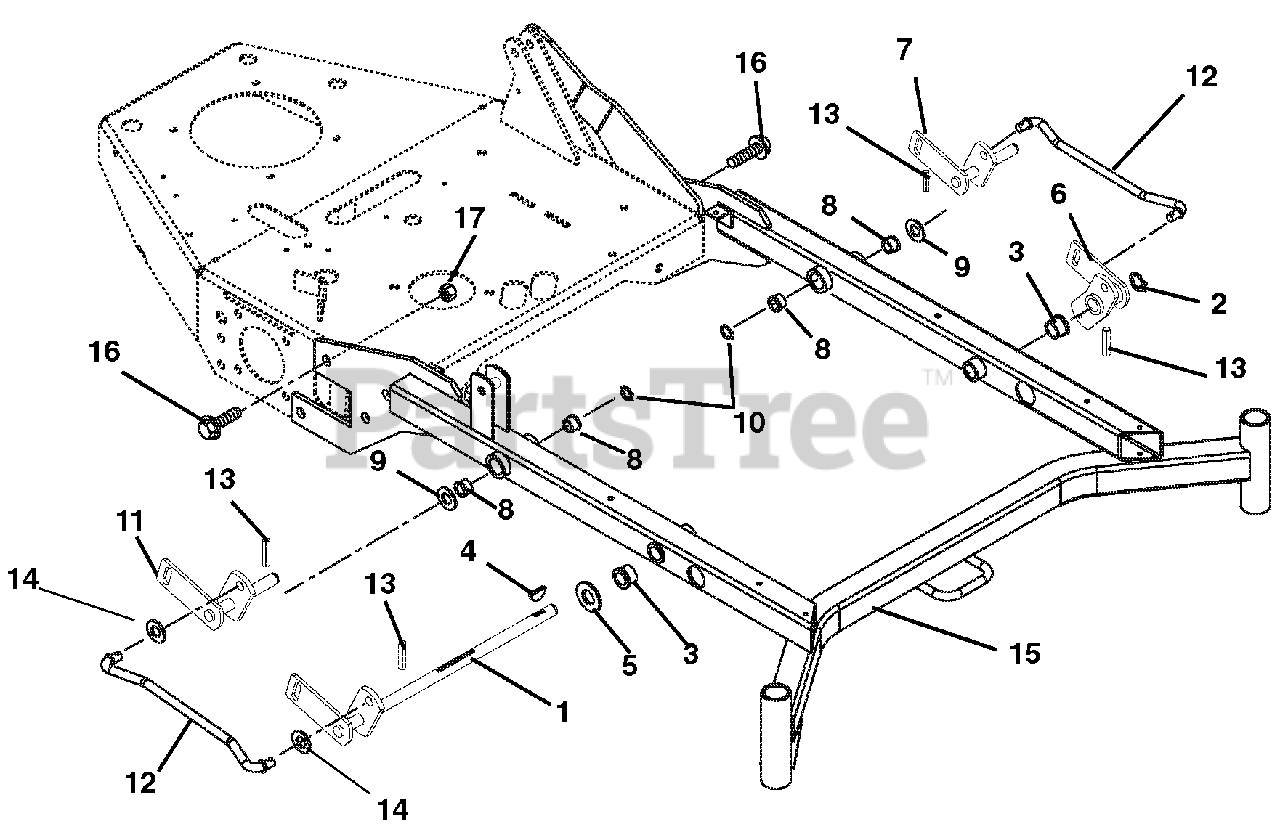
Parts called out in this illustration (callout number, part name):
1	Lift, Mower
2	Ring, Retaining-External 1.00 x .078
3	Bushing 1.00 x 1.25 x 1.937
4	Key, Woodruff .25 x 1.00
5	Washer, Flat-Steel- 1.062 x 2.0 x .134
6	Mower, Lift Arm
7	Weldment, Rear Lift Arm-Left Hand
8	Bushing, Flange-Nylon .762 x 1.0 x .580 x 1.48
9	Washer, Hardened-Steel .758 x 1.23 x .031
10	Ring, Retaining-External .689 x .077
11	Weldment, Rear Lift Arm- Right Hand
12	Rod, Lift Assist 16.35"
13	Pin, Roll .250 x 1.25
14	Washer, Flat-Steel .630 x 1.005 x .062
15	Weldment, Mower Frame 50/60
16	Bolt, Hex .62-11 x 1.50 Grade 5
17	Nut, Locking-Nylon .625-11
